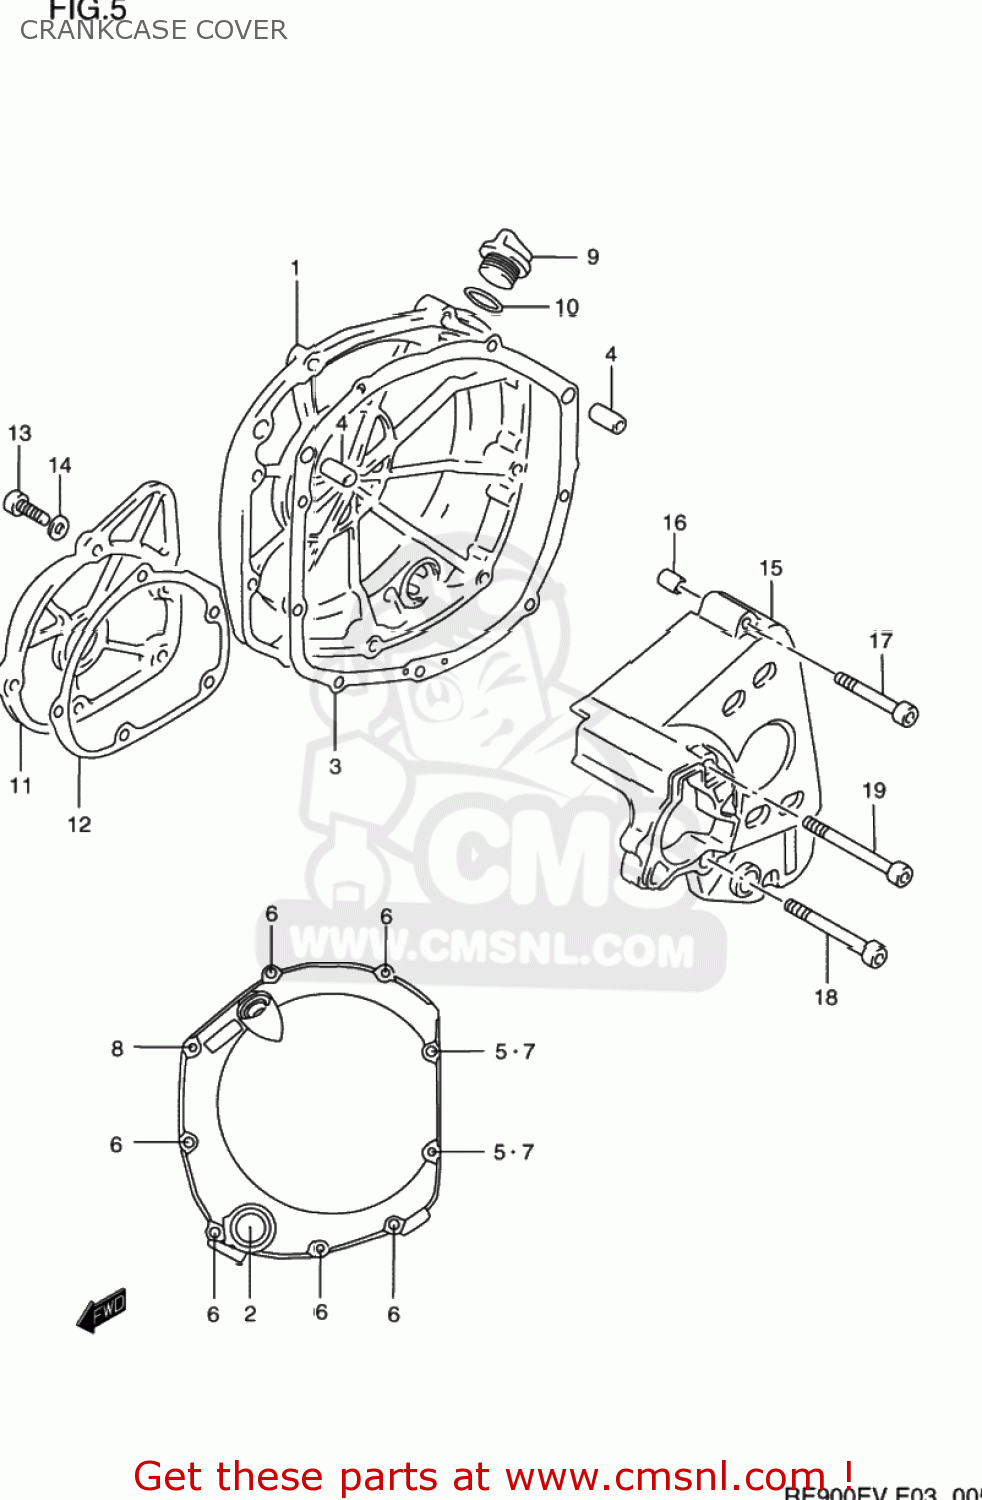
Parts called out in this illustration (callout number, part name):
1	COVER,CLUTCH
2	LENS,OIL LEVEL CHECK
3	GASKET,CL COVER (NAS)
4	PIN
5	GASKET(5.8X11X1.2) (NAS)
6	BOLT,CL.COVER
7	BOLT
8	BOLT
9	PLUG
10	O RING(D:3.1,ID:16.8)
11	COVER,SIGNAL GENERATOR
12	GASKET,SIGNAL GEN COVER
13	BOLT(6X22)
14	GASKET(5.8X11X1.2) (NAS)
15	COVER,ENGINE SPROCKET
16	PIN
17	BOLT,CL.COVER
18	BOLT
19	BOLT
